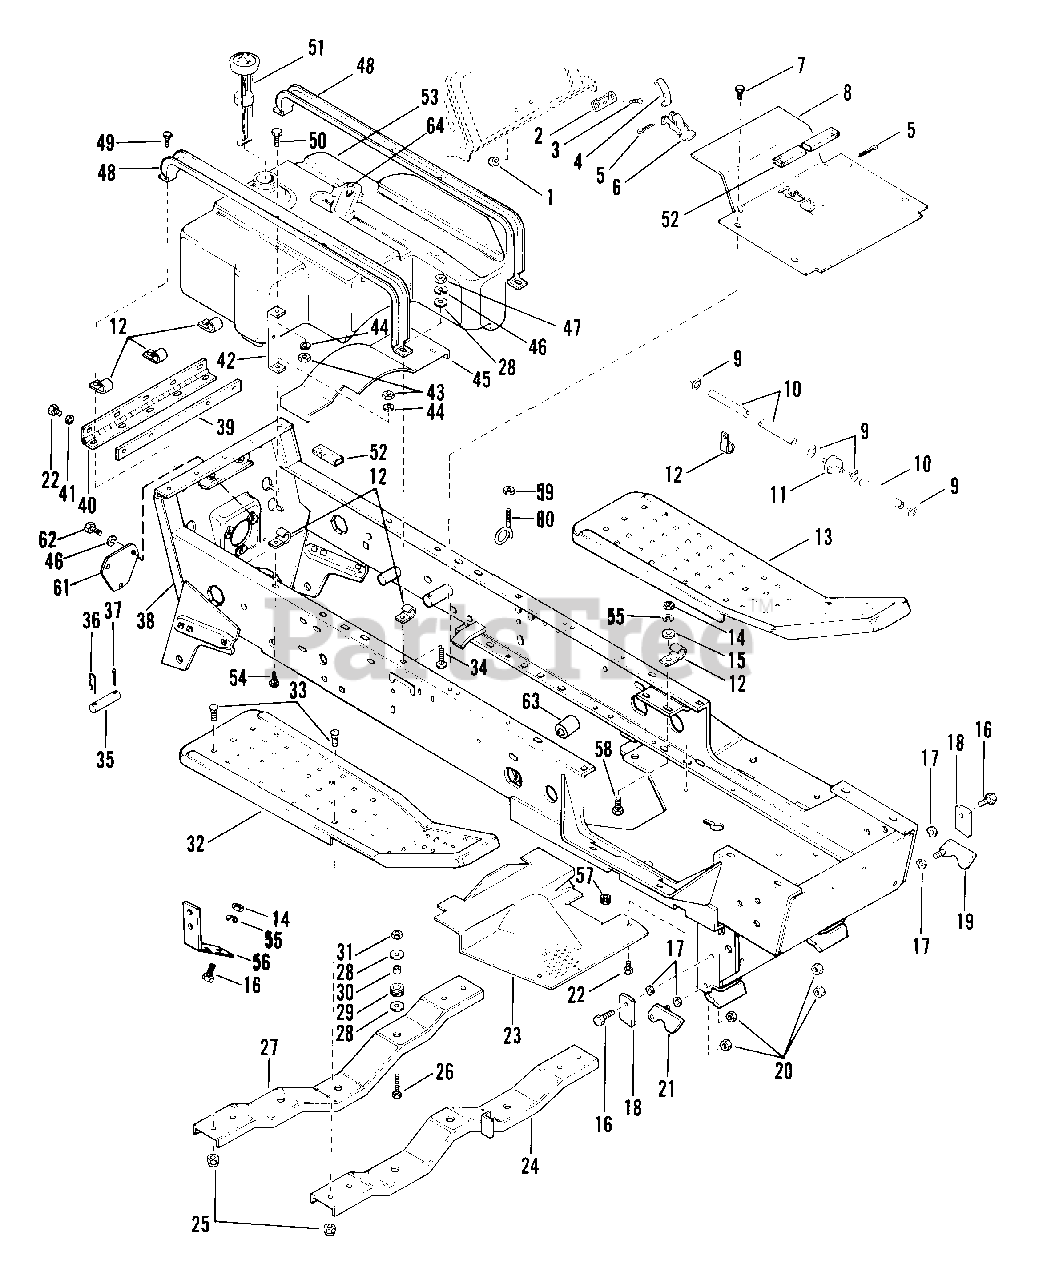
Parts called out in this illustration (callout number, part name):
1	NUT-LK DUAL FACE 10-24 PL
3	SCR-MCH 10-24X.50 SLRH PL
4	SPRING - DECK LATCH
5	PIN-COTR .12 X 1.25 PL
6	LEVER - DECK LATCH
7	SCR-TAP .250-20X.37 HWH PL TR
8	FLOOR PLATE
9	CLAMP-HOSE WIR.490/.510X.092#8
10	FUEL LINE 1/4 X 67"
11	FUEL FILTER
12	J-CLAMP
13	L.H. RUNNING BOARD
14	NUT-HEX .375-16
15	WSHR-FL-STL .438X1.0X.083 PL
16	BLT-HEX .38-16X1.00 PL
17	SPRING WASHER
18	LOCK STOP
19	LATCH LH
20	NUT-LK TOP .375-16 GR C YWZC
21	LATCH RH
22	SCR-TAP .312-18X.50 HWH PL TR
23	SCREEN
24	FRONT CHANNEL
25	NUT-FLG. .312-18 PL
26	BLT-HEX .31-18X1.25 PL GR2
27	REAR CHANNEL
28	WSHR-FL-STL .38X.875X.083 PL
29	GROMMET .438ID X .688 OD
30	SPACER .318X.430X.375
31	NUT-LK .312-18 GR A PL
32	R.H. RUNNING BOARD
33	BLT-RDHDSQSHNK .31-18X.50 YZ
34	BLT-RDHDSQNK .31-18X.75 SHT PL
36	PIN-HAIR INT .14X.4X2.75
37	PIN-COTR .12X1.0 PL
38	STRAP
40	HINGE-2" X 12.88 YWZC
41	WSHR-FL-STL.344X.688X.065PL
42	SUPPORT
43	NUT-HEX .250-20 PL
44	WSHR-LK .250X.077 HVY PL
46	WSHR-LK .312X.097 PL HVY
47	NUT-HEX .312-18
48	CHANNEL
49	SCR-TAP .312-18X.75 HWH PL TR
50	SCR .25-20X.75 TS PH PL
51	GAS GAUGE & CAP
52	FOAM TAPE
53	GAS TANK ASSEMBLY
54	BLT-RDHDSQNK .25-20X.75
55	WSHR-LK .375X.115 HVY PL
56	BRACKET
57	GROMMET 1.0ID X 1.38 OD
58	BLT-RDHDSQNK .38-16X1.0 PL
59	CABLE SUPPORT
60	NUT-LK-FLG .250-20 PL
61	COVER
62	BLT-HEX .31-18X.75 PL GR2
63	BSHG-SLV .750X.814X .750 BRZ
64	FITTING - GAS TANK
